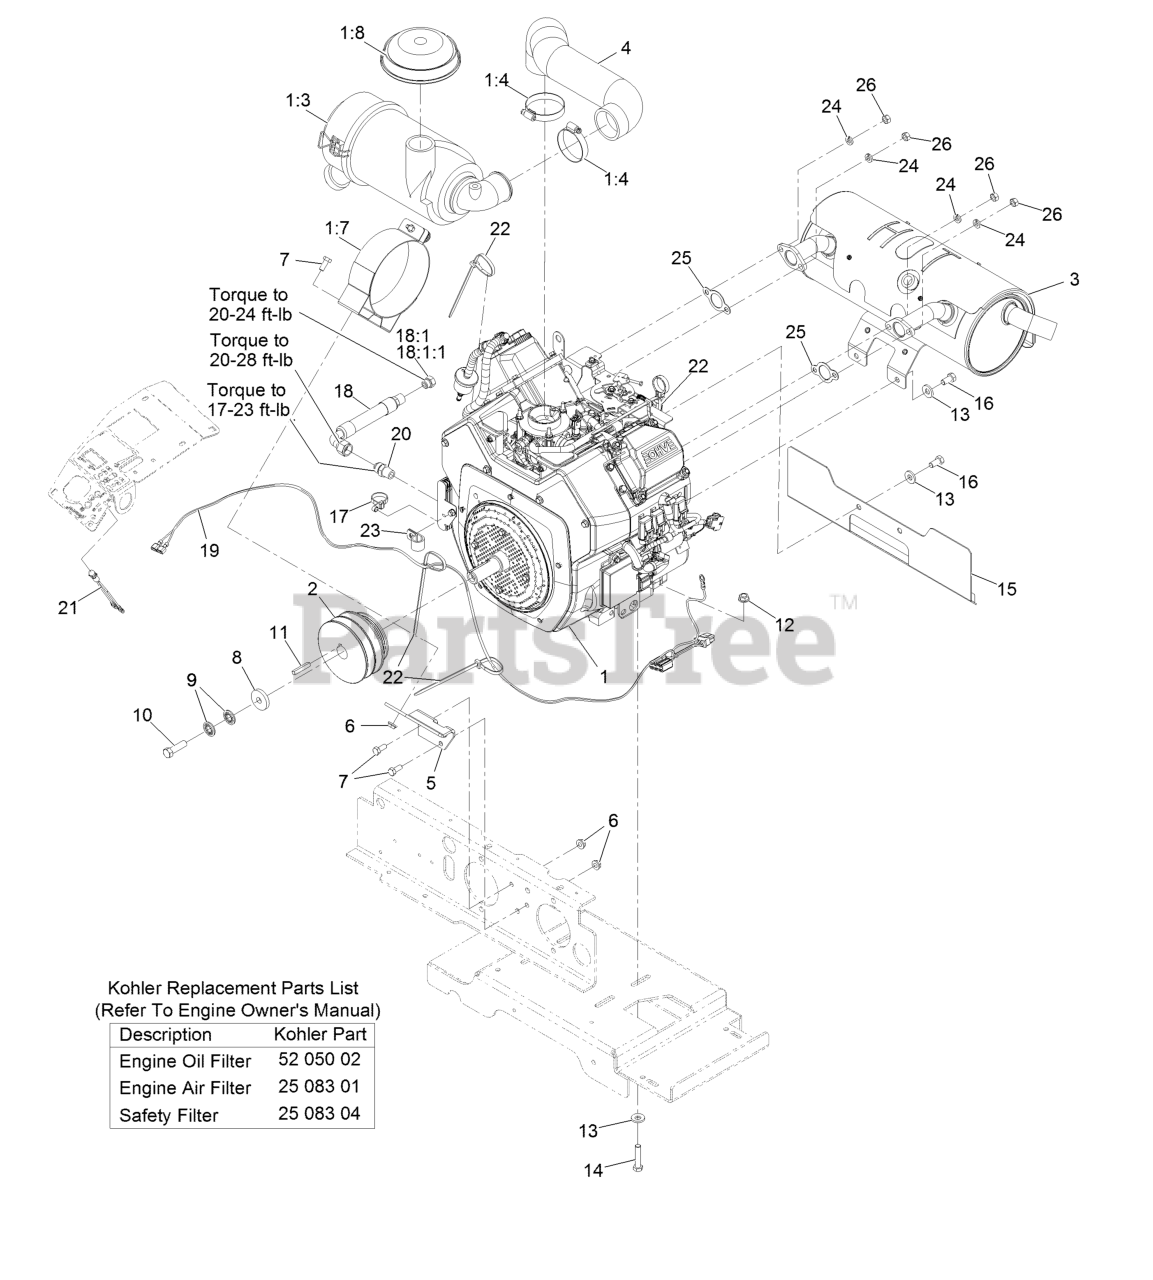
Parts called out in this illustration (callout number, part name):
1:3	Air Cleaner Canister ASM
1:4	Clamp-Hose
1:7	Bracket-Filter, Air
1:8	Asm-Hood Air Intake W/Clamp
2	Sheave-Engine
3	Muffler
4	Hose-Air Intake
5	Bracket-Filter, Air
6	Nut-Whizlock 5/16-18
7	Screw-HH 5/16-18 X 3/4
9	Washer-Spring Disc 7/16
10	Screw-HH 7/16-20 X 1 1/2
11	Key-Machine 1/4 X 1/4 X 1 1/2
12	Nut-Whizlock 3/8-16
13	Washer-Spring Disc 3/8
14	Screw-HH 3/8-16 X 1 3/4
15	Shield-Exhaust
16	Screw-HH 3/8-16 X 3/4
17	Tie-Cable
18	Oil Drain Hose ASM
18:1	Plug-W/O-Ring
18:1:1	O-Ring
19	Harness-Light Indicator (Efi)
20	Fitting-Straight
21	Indicator-Red LED
22	Tie-Cable 7 15/16 (Large)
23	Clip-Loom 5/8
24	Washer-Lock 5/16 Heavy
25	Gasket-Exhaust
26	Nut-Hex M8-1.25
